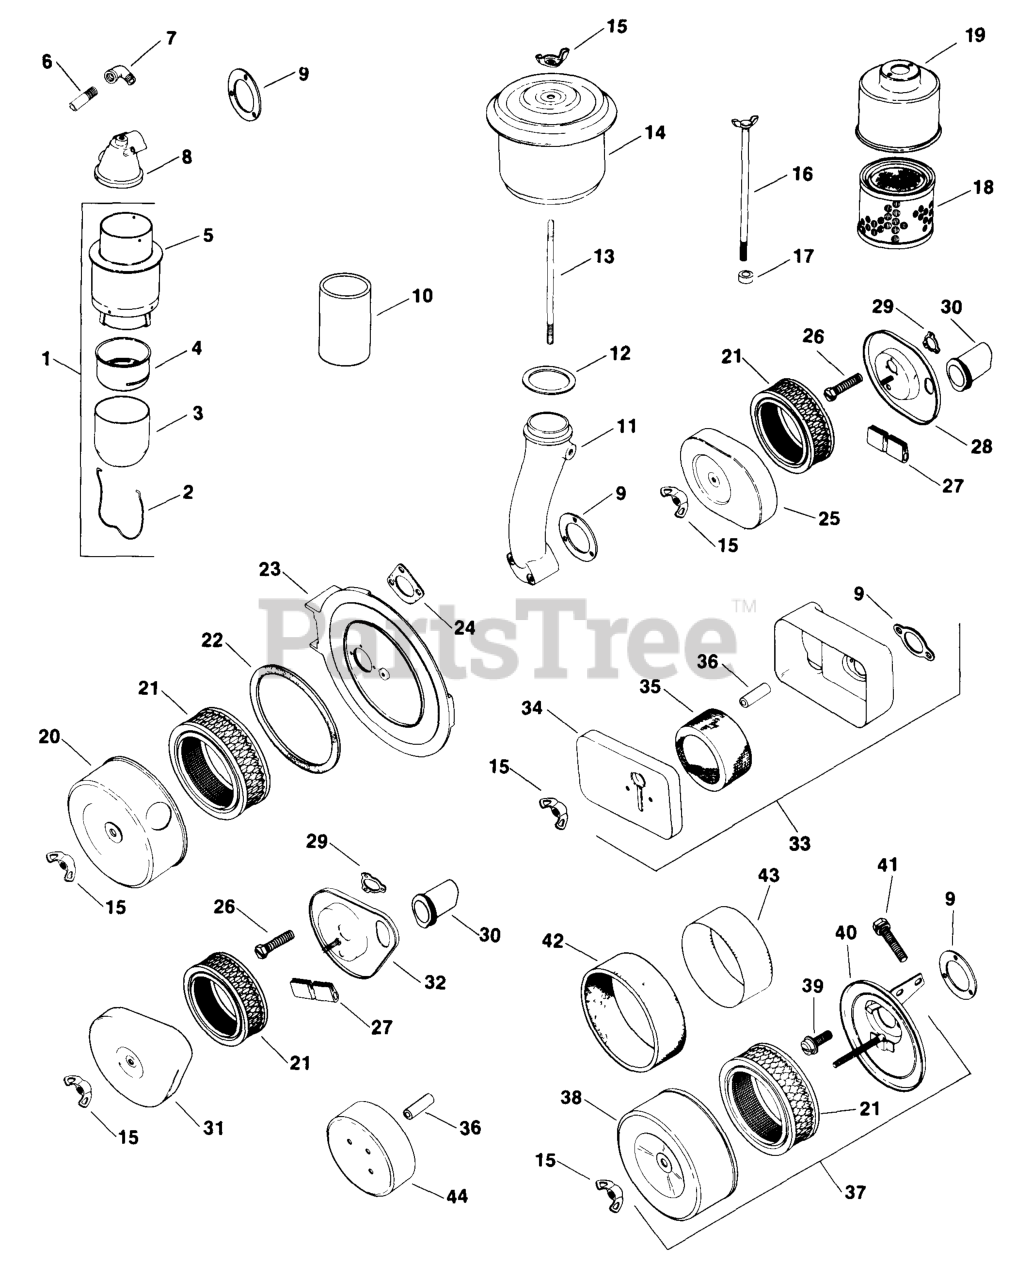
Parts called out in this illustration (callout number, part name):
15	NUT, WING 1/4-20 USE 25 100 15-S
26	SCREW, WASHER HD TAP #8-32X3/8" USE 25 086 99-S
27	SEAL-(#DSC)
29	GASKET - DISCONTINUED
32	BASE - DISCONTINUED
